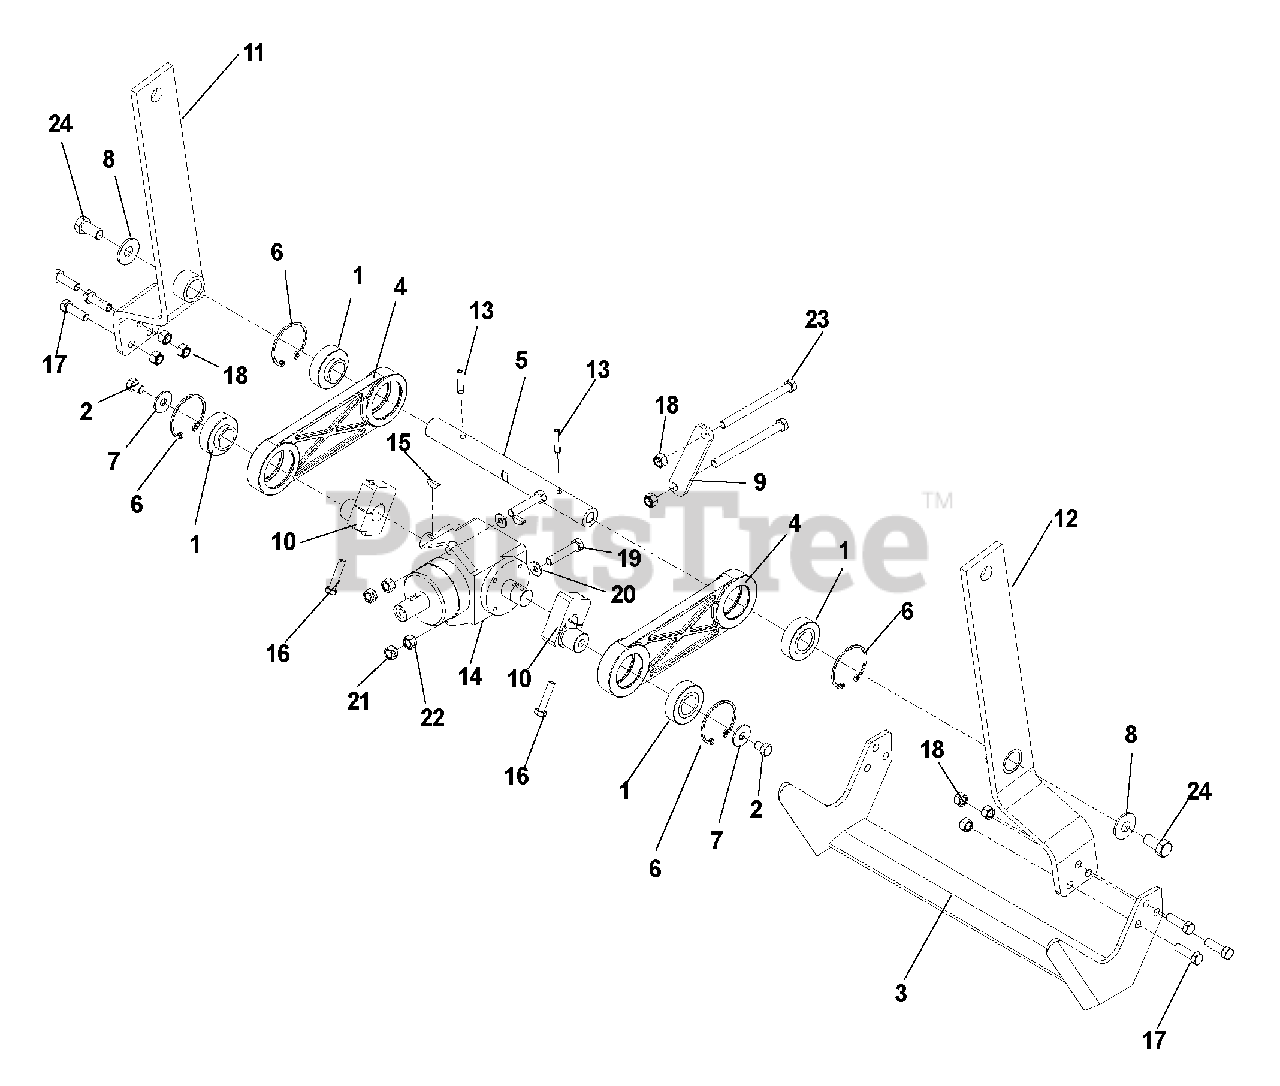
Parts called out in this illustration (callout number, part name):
1	BUSHING
2	HCS, 3/8-16 X 1/2, GR5
4	LINK, CONNECTING
5	SHAFT, BLADE
6	SNAP RING, 52MM
7	SPRING WASHER, 3/8
8	SPRING WASHER, 1/2
11	BLADE ARM, RIGHT
12	BLADE ARM, LEFT
13	SPRIAL PIN, 1/4 DIA. X 1 1/4
15	KEY, WOODRUFF #9
16	HCS, 5/16-18 X 1 1/2, GR5
17	HCS, 3/8-16 X 1 1/4, GR5
18	NUT, 3/8-16, NYLOC
19	HCS, 3/8-24 X 1 3/4, GR8
20	WASHER, 3/8, SAE
21	NUT, 3/8-24, GR2
22	NUT, 3/8-24, CENTERLOCK, GR5
23	HCS, 3/8-16 X 4 1/2, GR5
24	HCS, 1/2-13 X 1, GR5
